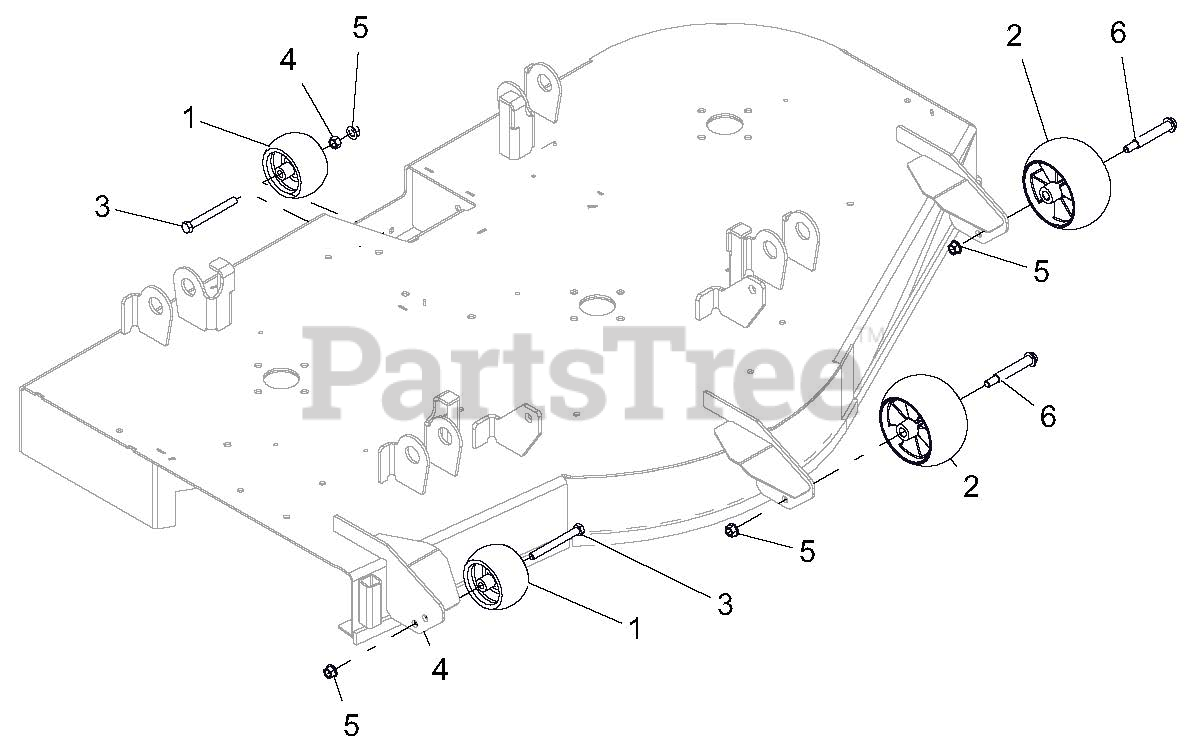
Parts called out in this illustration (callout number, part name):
2	ANTI-SCALP WHEEL - 5XOS
3	BLT-HEX .38-16X3.50 GR5 YWZC
4	NUT-HEX .38-16 YWZC
5	NUT, LK-TOP-FLG .38-16 YWZC
6	BLT-SHLDR .38-16X2.50 HWH G5YZ
